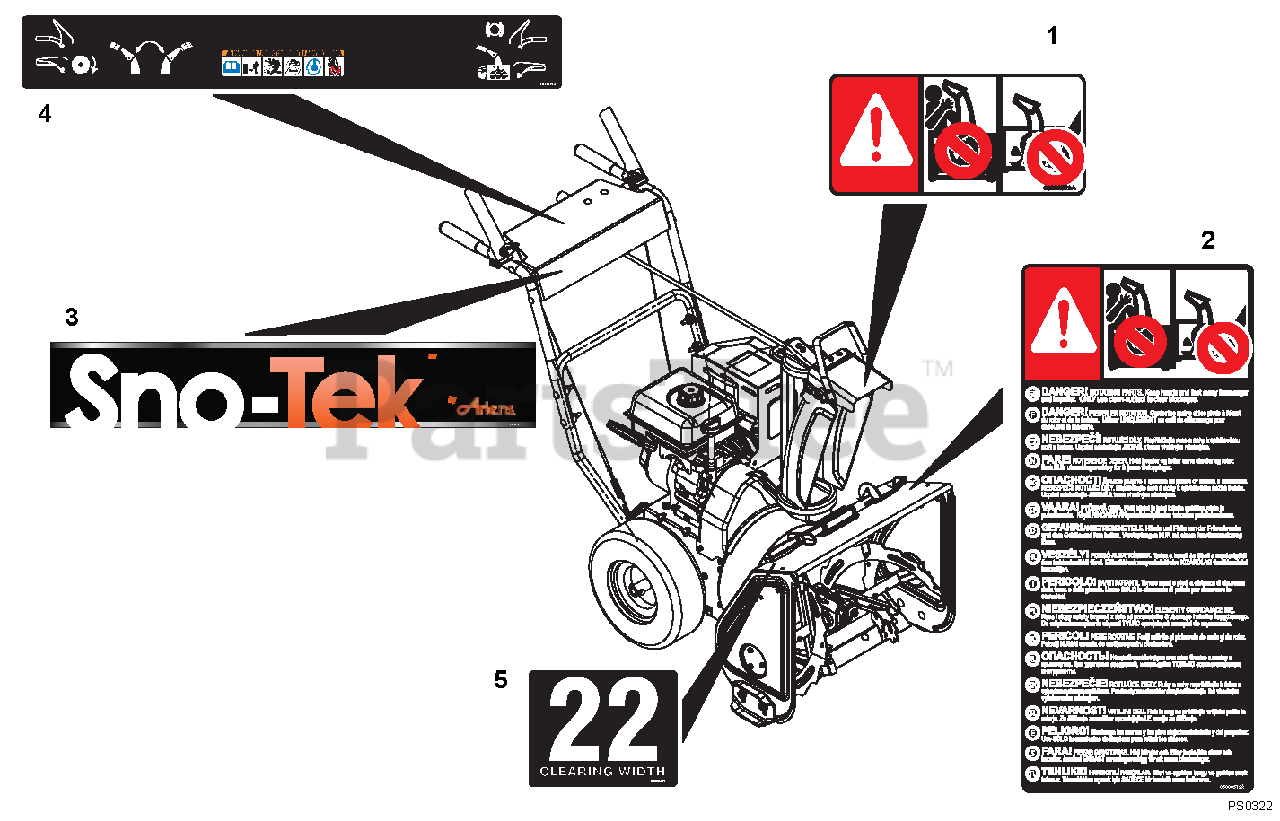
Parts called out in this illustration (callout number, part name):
1	DECAL, DANGER
2	DECAL, DANGER - ROTATING PARTS
3	DECAL, DASH - SNO-TEK
4	DECAL, CTRL PANEL, SINGLE SPD
5	DECAL, HOUSING SNO-TEK 22
